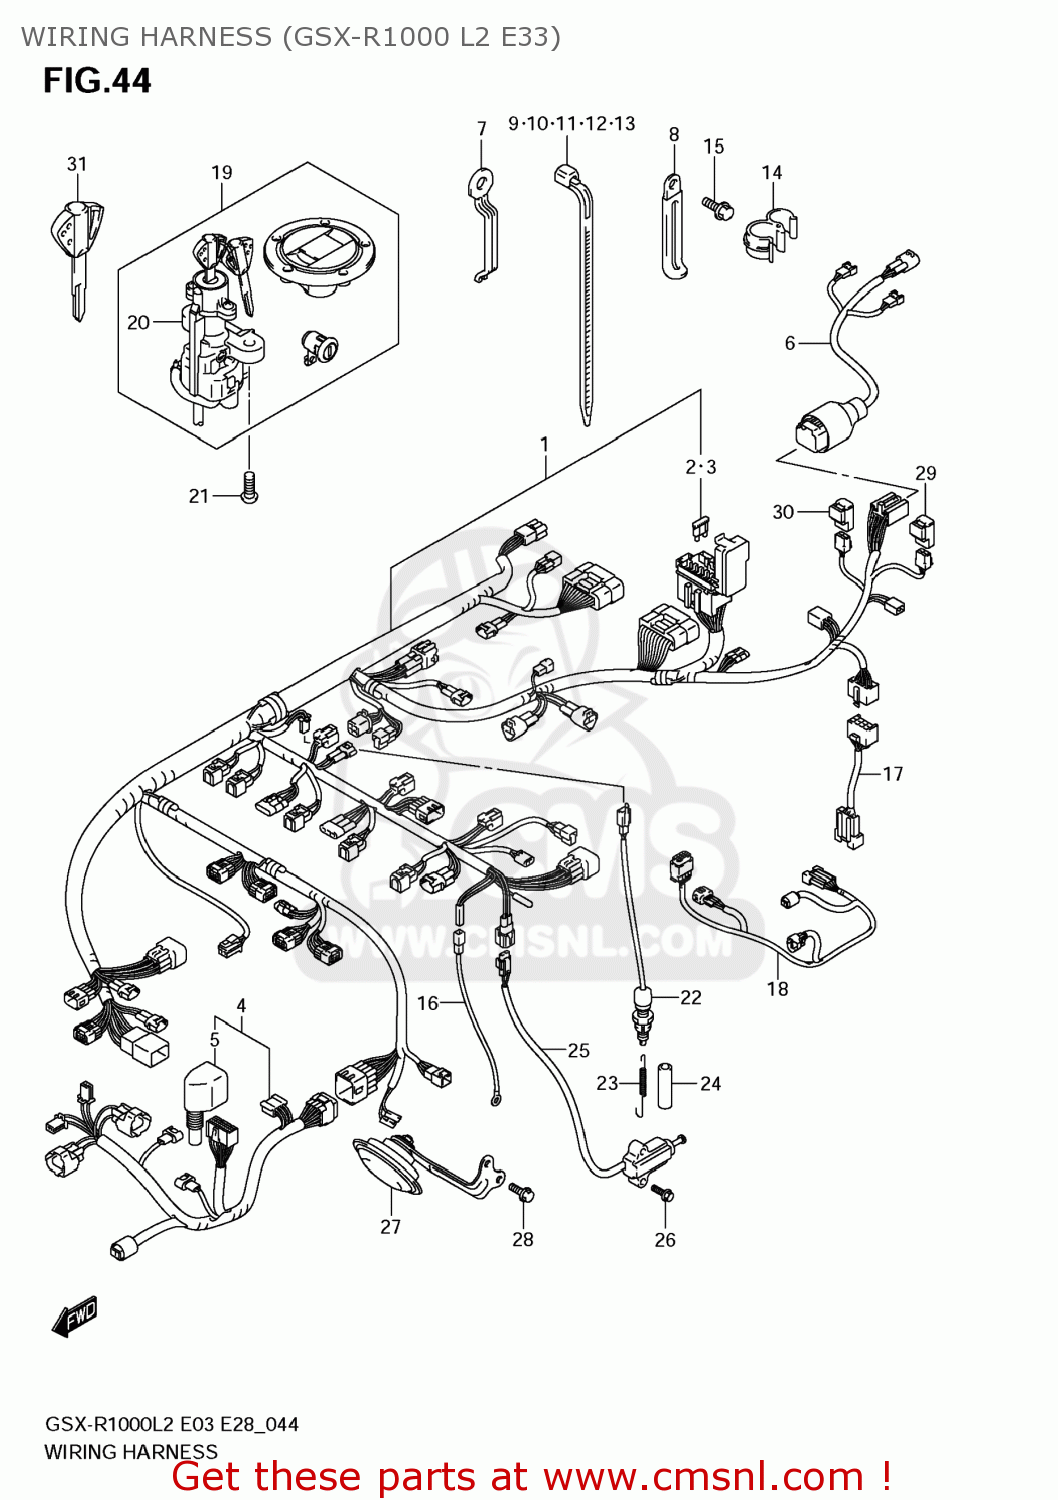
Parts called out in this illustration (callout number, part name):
1	HARNESS,WIRING
2	FUSE(10A)
3	FUSE(15A)
4	HARNESS,WIRING NO.2
5	COVER,CONNECTOR
6	WIRE,RR COMB
7	CLAMP
8	CLAMP(L:45)
9	CLAMP(L:125)
10	CLAMP(L:95)
11	CLAMP(L:165)
12	CLAMP(L:190)
13	CLAMP(L:190)
14	CLAMP
15	BOLT
16	WIRE,OIL PRESSURE SWITCH LEAD
17	WIRE,RELAY LEAD
18	WIRE,ISC LEAD
19	LOCK SET
20	LOCK ASSY,STEERING
21	BOLT(8X20)
22	SWITCH ASSY,STOP LAMP
23	SPRING
24	HOSE(5X8.2X600)
25	SWITCH ASSY,SIDE STAND
26	BOLT(6X20)
27	HORN ASSY
28	BOLT
29	RELAY ASSY
30	RELAY ASSY
31	KEY,BLANK(IMMOBII)
